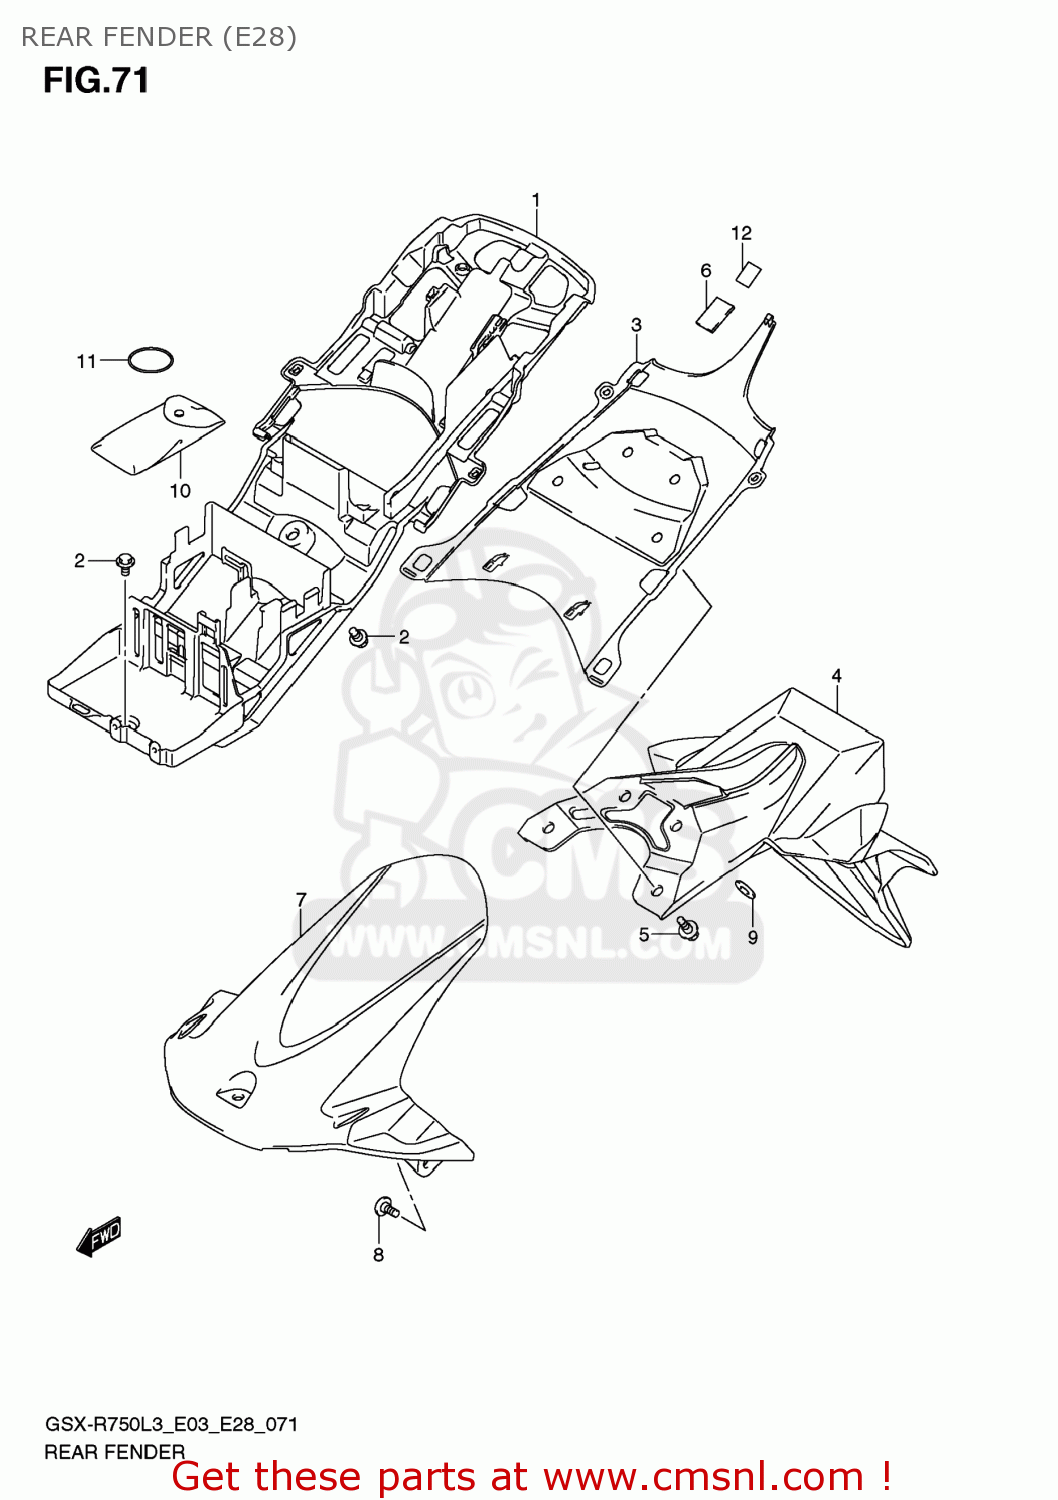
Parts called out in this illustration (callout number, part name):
1	FENDER,RR FR
2	BOLT(6X12)
3	COVER,RR FENDER FR
4	FENDER,RR RR
5	BOLT(6X17.8)
6	CUSHION,FUEL TANK ATTACHMENT
7	FENDER,RR LWR
8	SCREW(6X16)
9	WASHER(6.5X20X1.2)
10	TOOL ASSY
11	O RING(D:3.5,ID:56.5)
12	FASTENER,COWLING
